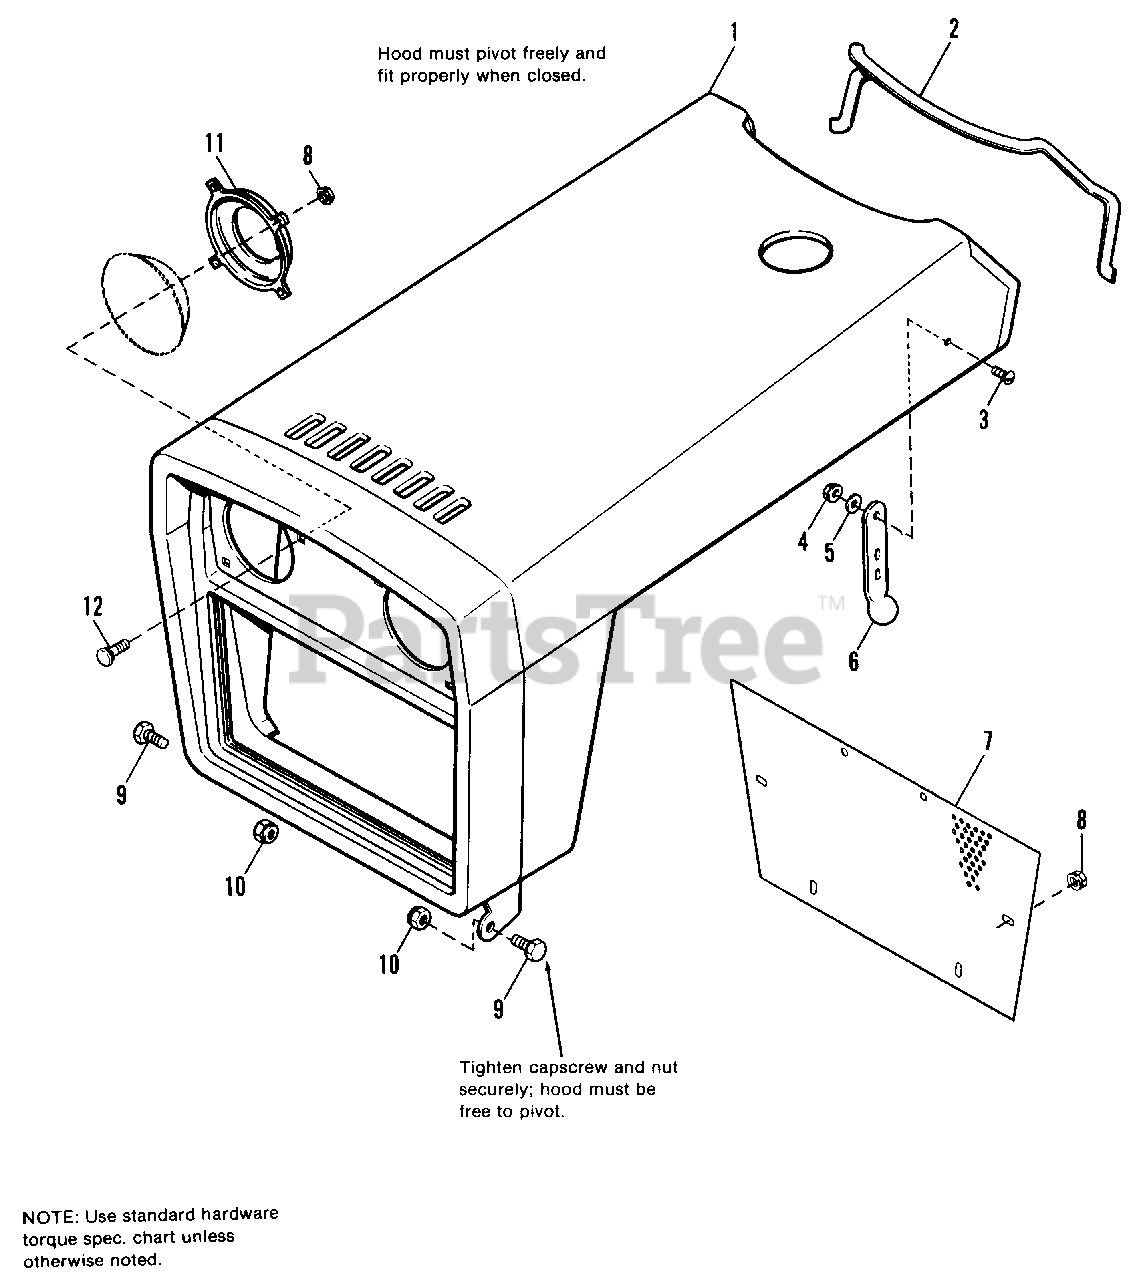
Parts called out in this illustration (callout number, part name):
1	HOOD & GRILLE ASSY.
2	MOULDING, Hood
3	SCREW, Truss Hd., #10-32 x 1/2
4	LOCKNUT, Hex, #10-32
5	WASHER, Special
6	STRAP, Hood
8	LOCKNUT, Pal
9	CAPSCREW, Hex Hd., 3/8-16 x 1
10	LOCKNUT, Hex, 3/8-16
11	BRACKET, Headlight
12	BOLT, Carriage, #10-29 x 12
